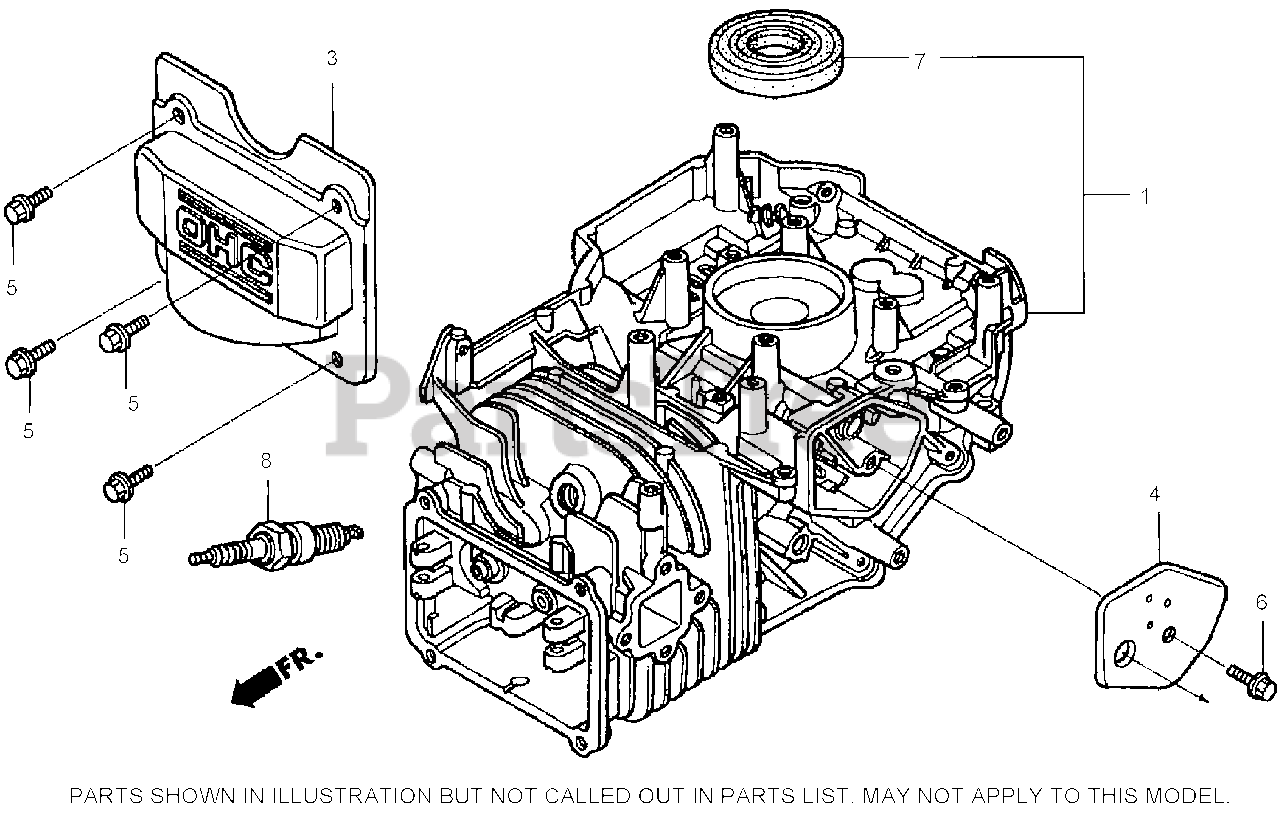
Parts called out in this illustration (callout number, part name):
1	CYLINDER ASM.
3	COVER, HEAD
4	COVER, BREATHER (BREATHER VALVE ASM.)
5	BOLT-FLANGE (6X12)
6	BOLT-FLANGE (6X14)
7	OIL SEAL (25.4X62X6)
8	SPARK PLUG (BPR6ES)
